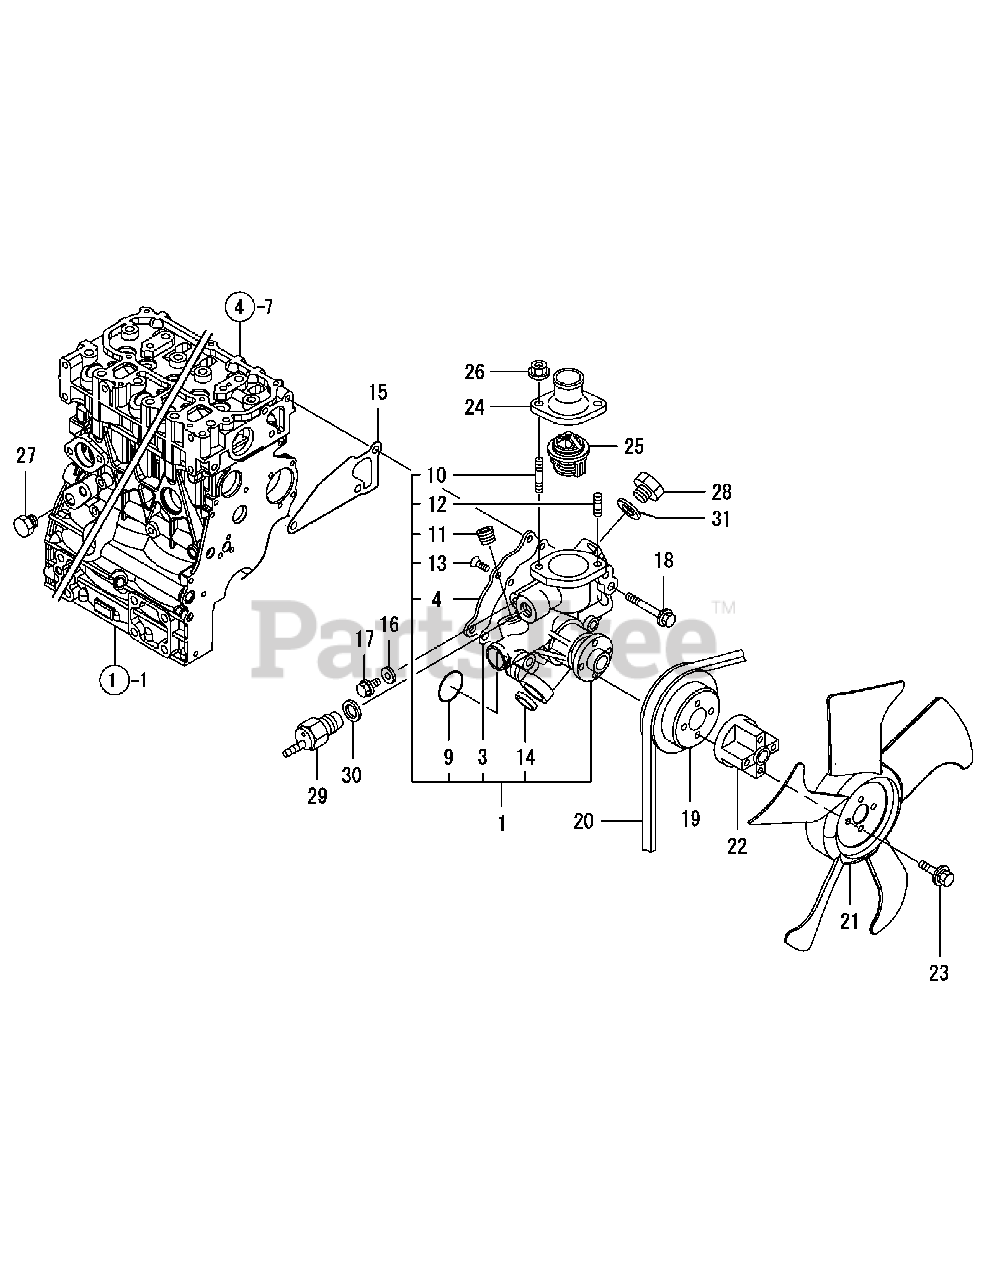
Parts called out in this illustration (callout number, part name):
1	PUMP ASSY, WATER
4	COVER,WATER PUMP
11	PLUG, DRAIN R03
12	STUD M 8X 20 PLATED
15	GASKET, WATER PUMP
16	GASKET 8, ROUND
17	BOLT M 8X 12 PLATED
18	BOLT M 8X 50 PLATED
19	V-PULLEY, C.W.PUMP
21	FAN (D300, SUCTION)
23	BOLT M 6X 55 PLATED
24	COVER, THERMOSTAT
25	THERMOSTAT, 71C
29	SWITCH, THERMO(110 C)
